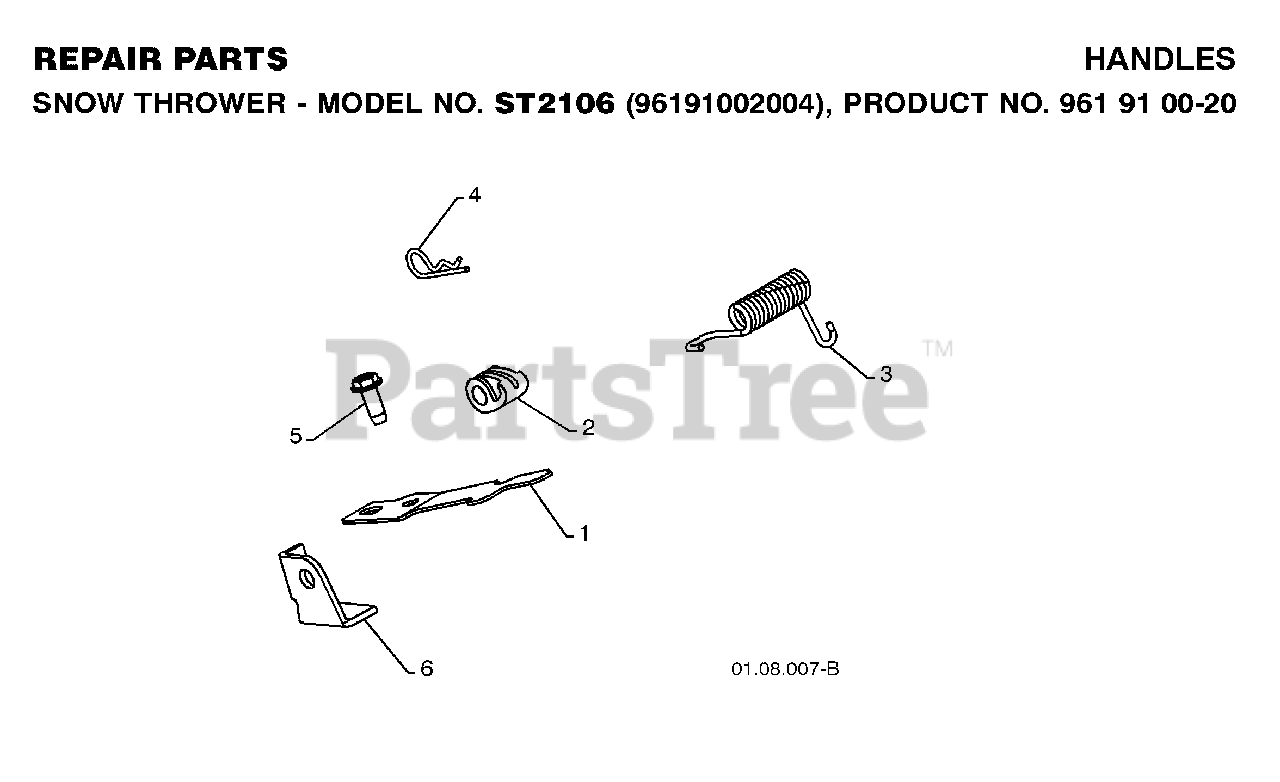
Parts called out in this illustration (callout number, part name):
1	SPRING.INTERLOCK
2	RP CAM.INTERLOCK.RELEASE
3	RP SPRING, TORSION
4	SPRING RETAINER
5	SCREW 14-20 X 5/8
6	STOP.INTERTLOCK
